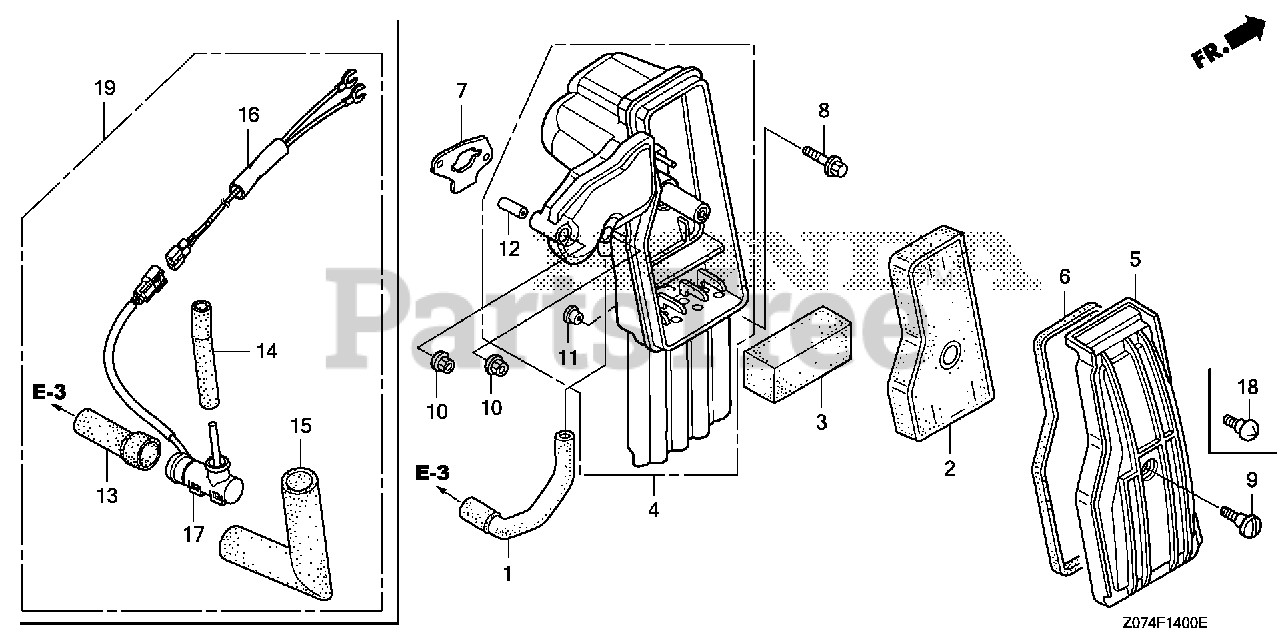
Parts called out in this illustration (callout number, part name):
1	TUBE, BREATHER
2	ELEMENT, AIR CLEANER
3	FILTER (OUTER)
4	HOUSING, AIR CLEANER
5	COVER, AIR CLEANER
6	SEAL A, AIR CLEANER COVER
7	GASKET, AIR IN. JOINT
8	BOLT, FLANGE (5X16)
9	BOLT, AIR CLEANER COVER (- SCREW)
10	NUT, FLANGE (5MM)
11	COLLAR, REFLECTOR SETTING
12	COLLAR, AIR CLEANER
13	TUBE A, BREATHER
14	TUBE B, BREATHER
15	INSULATOR L, BREATHER TUBE
16	SUB-WIRE ASSY.
17	HEATER ASSY., BREATHER (L)
18	SCREW, SPECIAL (6X16)
19	HEATER KIT, BREATHER
